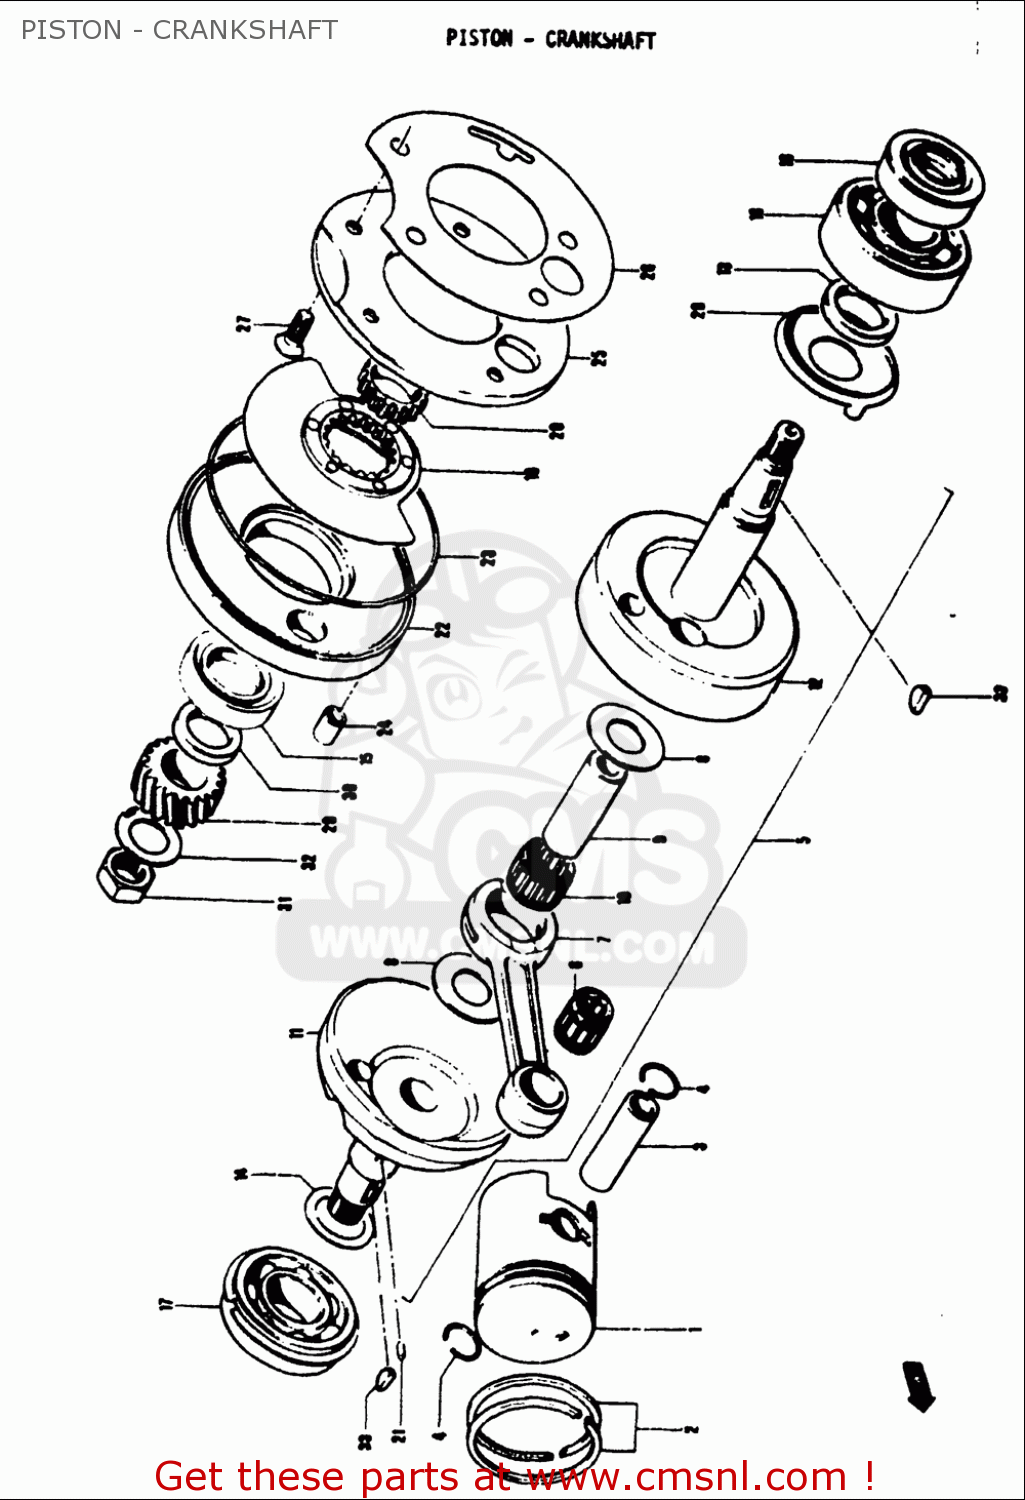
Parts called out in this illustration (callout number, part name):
1	PISTON SET(OS:1.0)
2	RING SET,PISTON
3	PIN,PISTON
4	RING,SNAP
6	BEARING(12X16X16)
7	ROD,CONNECTING
8	WASHER(16X32X1)
9	PIN,CRANK
10	BEARING(16X22X11.8)
13	SPACER(20X28X4.5)
14	SHIM(20X28X0.5)
15	OIL SEAL (25X44X7)
16	SEAL,OIL(19.6X37X8)
17	BEARING(20X52X15)
18	BEARING(20X47X14)
20	GUIDE,ROTERY VALVE
21	PIN
22	SEAT,CRANK OUTER VALVE
23	O RING(D:2.4,ID:100.6)
24	PIN
25	SEAT,INNER DISC VALVE
26	GASKET,ROTERY VALVE INNER SEAT (NAS)
27	SCREW
28	PLATE,CSHAFT OIL GUIDE
29	GEAR,PRIMARY DRIVE
31	NUT
32	WASHER
33	KEY
